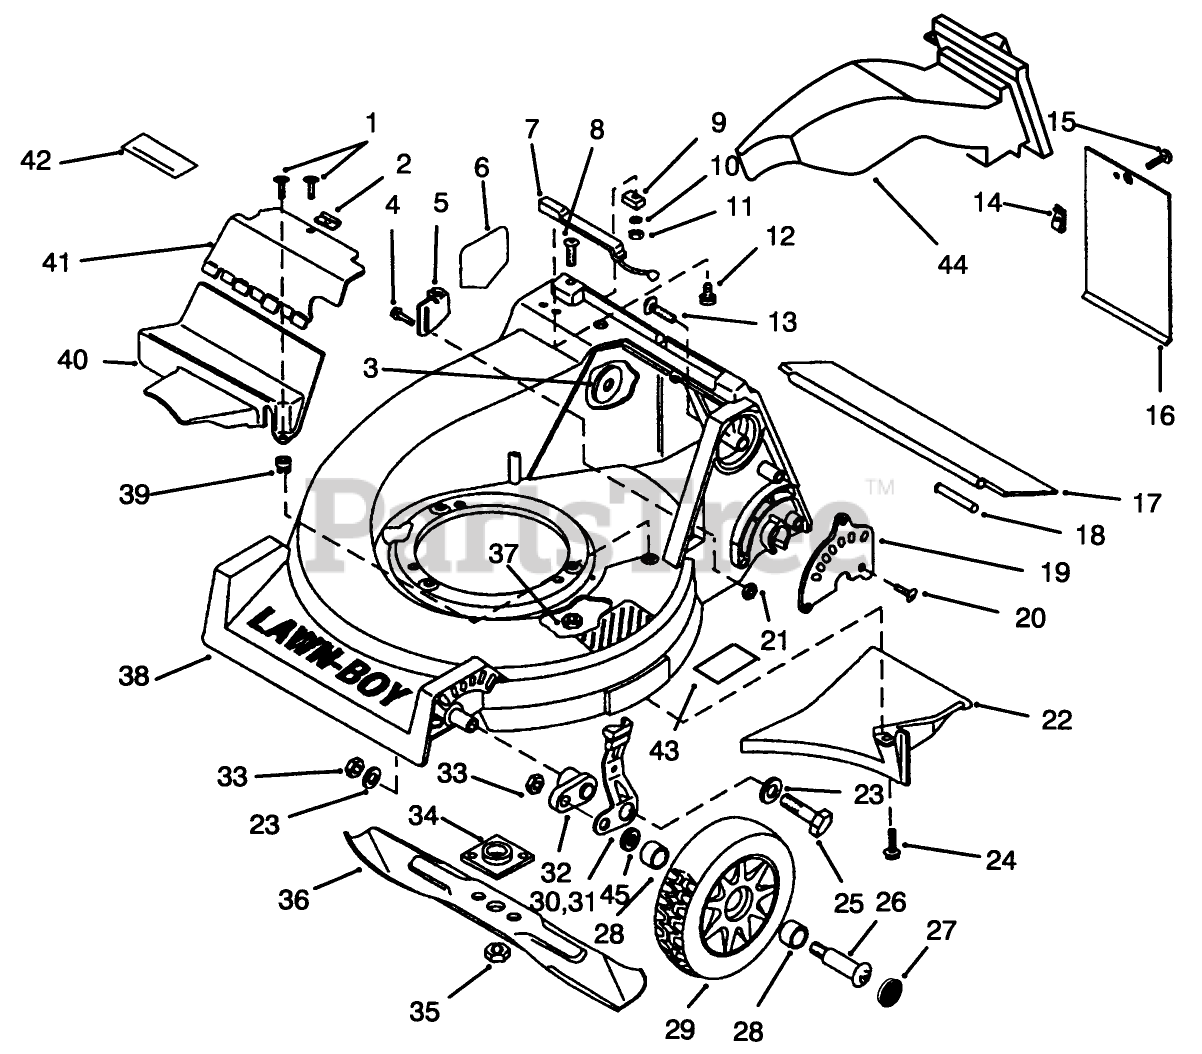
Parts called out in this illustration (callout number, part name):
2	NUT-SPEED
5	ANCHOR-CABLE
6	DECAL-DANGER
14	SPEED NUT LARSON
15	SCREW-CROSS RECESS
16	DOOR-ACCESS ELECT.
17	SHIELD - TRAILING
20	SCREW-BHTF
21	NUT-LOCK, NI
22	CHUTE BAFFLE NYL
23	WASHER-PLAIN
24	SCREW-HWH
26	BOLT-SHOULDER
29	WHEEL ASM
30	KNOB & SPRING CMS
32	ARM HGT ADJ *BLACK
33	NUT-JAM, LOCKING
34	PLATE AND COLLAR ASM
35	NUT-BLADE
37	NUT-LOCK, NI
38	HOUSING ASM.
39	NUT-CLIP
43	DECAL-INSTRUCTION, SAFETY
